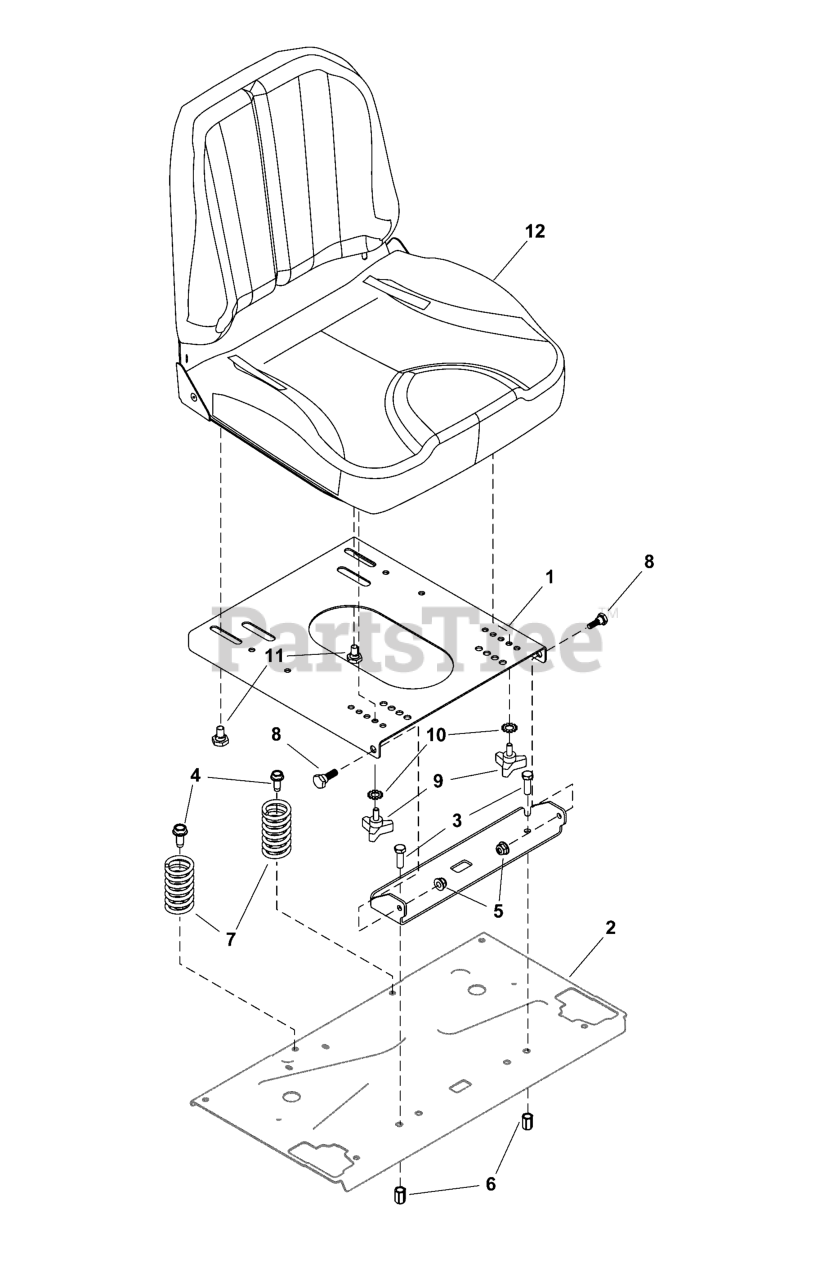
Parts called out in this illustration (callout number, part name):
1	BASE, Seat Plate Dual Knob
2	BRACKET, Seat Pivot
3	SCREW, 5/16-18 X 1.00 GR5
4	SCREW, 5/16-18 X .750, Hex Washer
6	NUT, Rivet,  5/16-18
7	SPRING, Compression
8	SCREW, .437, Shoulder
9	KNOB, Three Arm
10	WASHER, 5/16, EXT., Lock
11	SCREW, Shoulder
12	SEAT, (Black)
